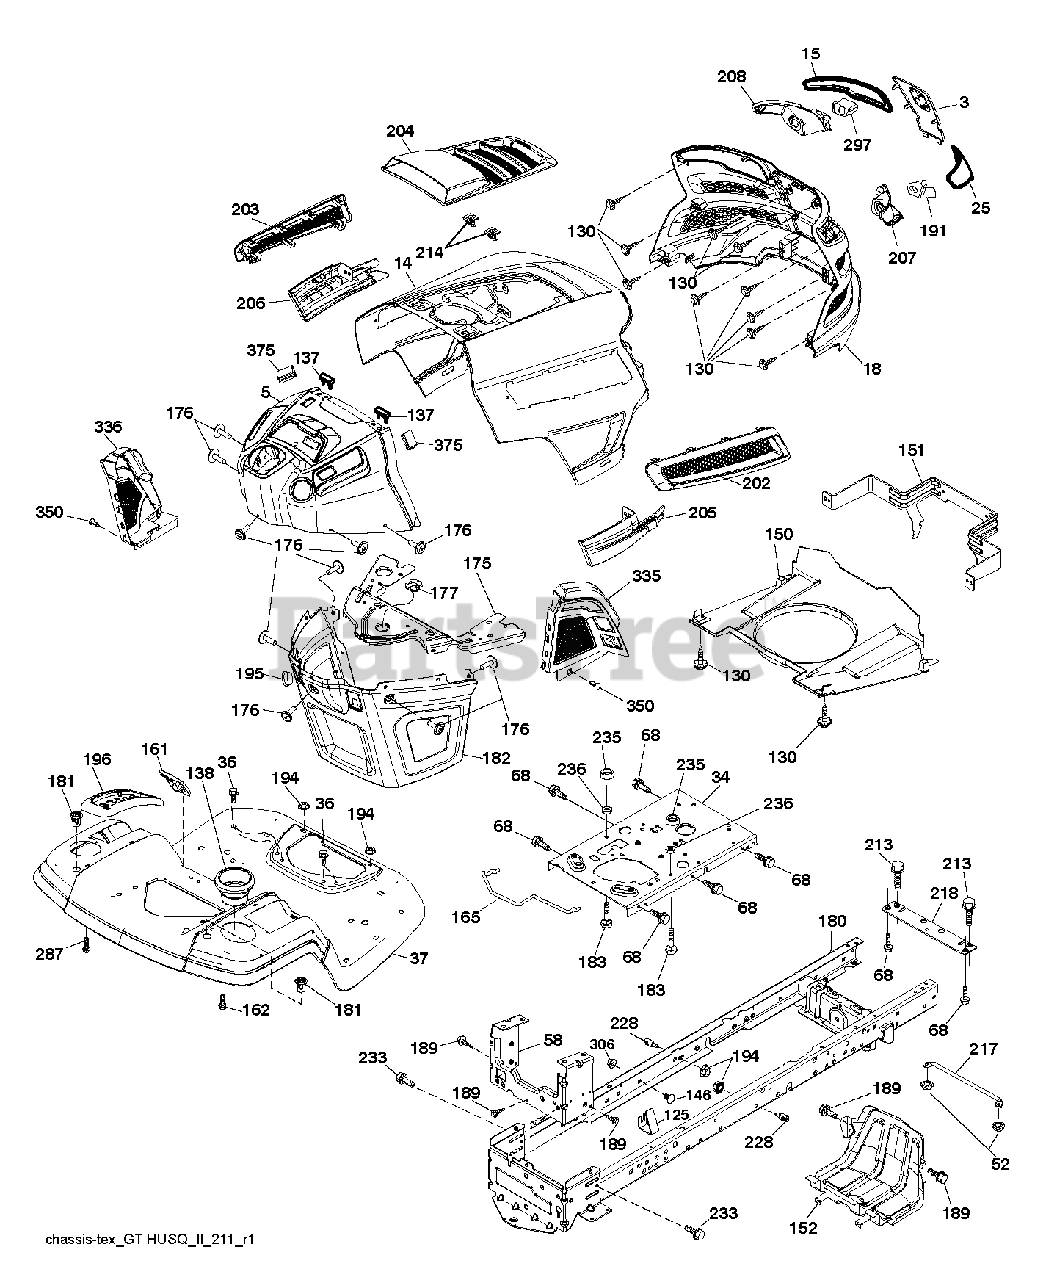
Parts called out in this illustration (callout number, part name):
3	APPLIQUE.SUBASM.GT.HUSQ.II
5	UPPER.GT2.SVC.MINDING.C-O.M;H
14	HOOD.ASM.HUSQVARNA.GT.TEX.ORAN
15	LENS.HEADLIGHT.LH.GTII.2011
18	GRILLE.SUBSTRATE.2011.
25	LENS.HEADLIGHT.RH.GTII.2011
34	PLATE.ENGINE.WELDED.CHASSIS
36	SCREW 5/16"
37	FENDER.ERGO.LT.W/CPH.W/FW.ORNG
52	LOCKNUT
58	DRAWBAR UPPER 2PC SMALL FENDER
68	SCR 5/16-18 X 1/2 SELFTAP ZN
125	CLIP.FUEL.LINE
130	SCREW.#10 X 0.750.BOS
137	BUMPER DASH
138	HOLDER.CUP.LT.GREY
146	BOLT.RDHD.SHT.SQNK.3/8-16X5/8
150	AIR.DUCT.GTV.BLACK
151	BRACKET.PIVOT.HOOD.GT.HUSQ.II
152	SHIELD.BROWNING.PNT.GT.V2
161	WINDOW.FUEL.LT.HUSQ.TEX.498
162	SCREW.HI-LO.CONSOLE
165	SUPPORT.TANK.REAR.W/TEX
175	Crossmember Plate
176	SCREW.#10-24X5/8.RN.QU
177	BUSHING STEERING
180	CHASS.WLDMNT.TL.12GA/2P.48/54
181	BUSHING.MNT.FEND.CRGO.TEX.49
182	DASH.LOWER.COMMON.12V.ADAPTOR
183	BOLT.5/16-18X1-1/4 FULL THD
189	SCREW, 3/8-16X3/4
191	INSERT.REFLECTIVE.RH.HUSQ.GTII
194	NUT LOCK HEX FLANGE 5/16-18
195	PLUG.HOLE.DASH.LOWER.12V.BLK
196	DECKLFT.CONSOL FULL ASSM GREY
202	VENT.SIDE.RH.GT.HUSQ.II.
203	VENT.SIDE.LH.GT.HUSQ.II.498
204	VENT.TOP.HUSQ.GT2
205	SIDE.TRIM.RH.GT.HUSQ.II
206	SIDE.TRIM.LH.GT.HUSQ.II.GRAY
207	BEZEL LIGHT.RH.GT.II.MYLAR
208	BEZEL LIGHT.LH.GT.II.MYLAR
213	BOLT
214	CLIP.RETAINER.TINNER.
217	ROD.PIVOT.HOOD
218	X-PIECE.HOOD.STOP.NON/
228	STUD.FASTNER.W/ANTI-ROTATE
233	BOLT.SHOULDER
235	SPACER FENDER
236	NUT.CENTERLOCK.5/16-
287	SCREW 1/4X20
297	INSERT.REFLECTIVE.LH.HUSQ.GTII
306	NUT LOCK FLG 3/8-16 UNC
335	COVER.LOWER.DASH.RH.BLACK
336	COVER-LH.LOWER.DASH.GT2.BLACK
350	CLIP.X-MAS.TREE
375	BUMPER CLIP-ON. DASH 1"
